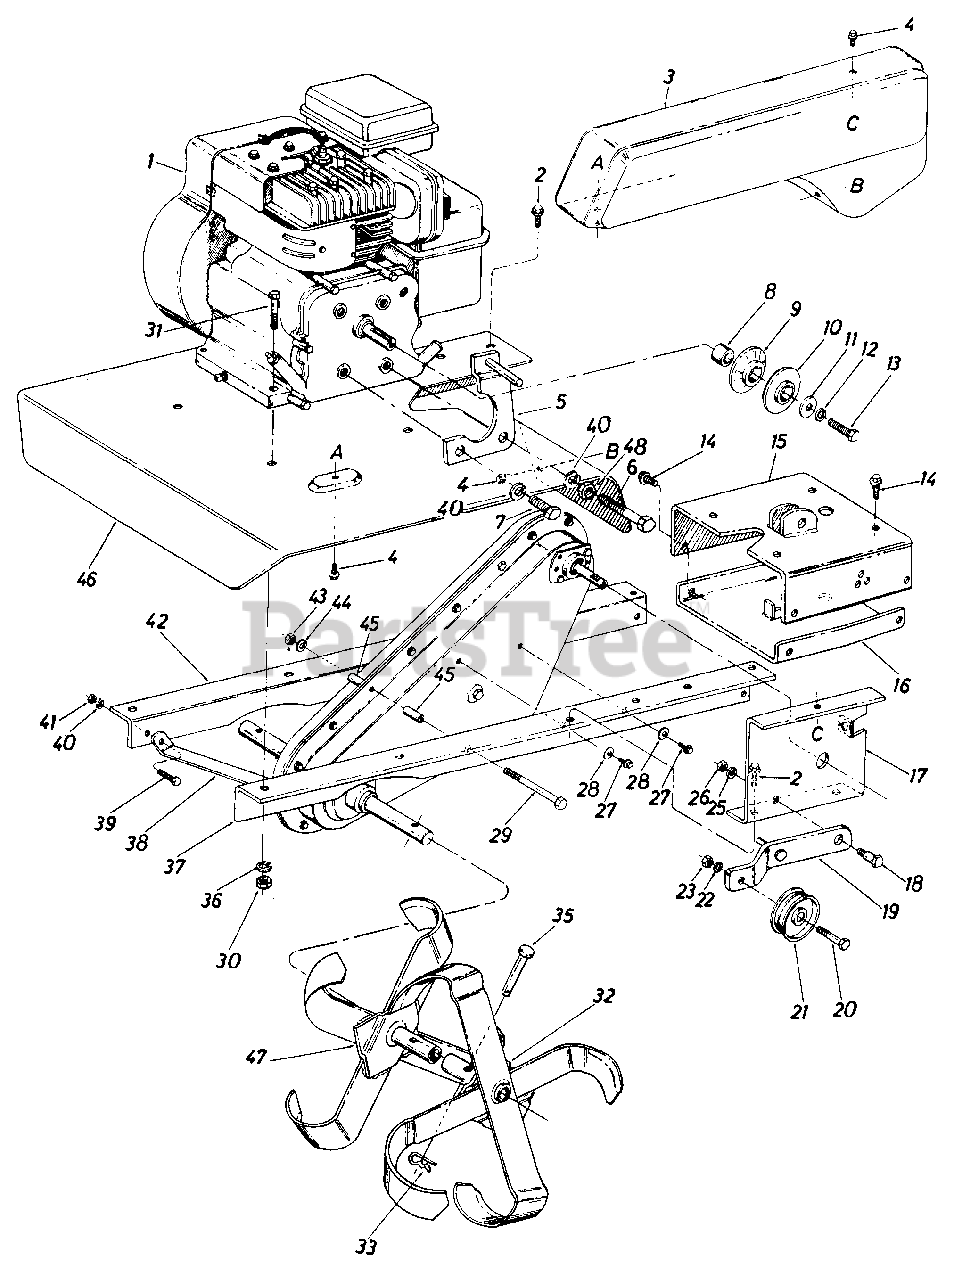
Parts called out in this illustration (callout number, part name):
1	Engine
2	Hex Wash. Hd. Self-Tap Scr. 5/16-24 x .50" Lg.
3	Belt Cover
4	Hex Wash. Hd. Self-Tap Scr. 1/4-20 x .50" Lg.
5	Belt Keeper Brkt. Ass'y.
6	Hex Bolt 5/16-24 x 2.25" Lg. (Gr. 5)
7	Hex Bolt 5/16-24 x .62" Lg. (Gr. 5)
8	Spacer
9	Pulley Half
10	Pulley Half
11	Fl-Wash. 3/8" I.D. x 1.25" O.D. x .100
12	L-Wash. 3/8" I.D.
13	Hex Bolt 3/8-24 x 1.00" Lg.
14	Hex Wash. Hd. Self-Tap Scr. 318-24 x 7/8" Lg.
15	Handle Mounting Brkt. Ass'y.
16	U-Channel Brkt. Ass'y.
17	Idler Mounting Brkt.
18	Shld. Bolt
19	Idler Brkt. Ass'y.
20	Hex Bolt 3/8-16 x 1.50" Lg.
21	Idler Pulley
22	L-Wash. 3/8" I.D.
23	Hex Nut 3/8-16 Thd.
25	L-Wash. 3/8" I.D.
26	Hex Nut 3/8-16 Thd.
27	Hex Wash. Hd. Self-Tap Scr. 1/4-20 x 50a Lg.
28	Belleville Wash. .26 I.D. x .75 O.D. x .060
29	Hex Bolt 5/16-18 x 3.0" Lg.
30	Hex Nut 5/16-18 Thd.
31	Hex Bolt 5/16-18 x 1.50" Lg.
32	See Tine Chart
35	Clevis Pin
36	L-Wash. 5/16" I.D.
37	Frame Rail-L.H.
38	Front Brace Brkt.
39	Hex Bolt 5/16-18 x 75" Lg.
40	L-Wash. 5/16" I.D.
41	Hex Cent. L-Nut 5/16-18 Thd.
42	Frame Rail-R.H.
43	Hex Cent. L-Nut 5/16-18 Thd.
44	L-Wash. 5/16" I.D.
45	Spacer
46	Tine Shield
47	See Tine Chart
48	Hex Nut 5/16-24 Thd.
